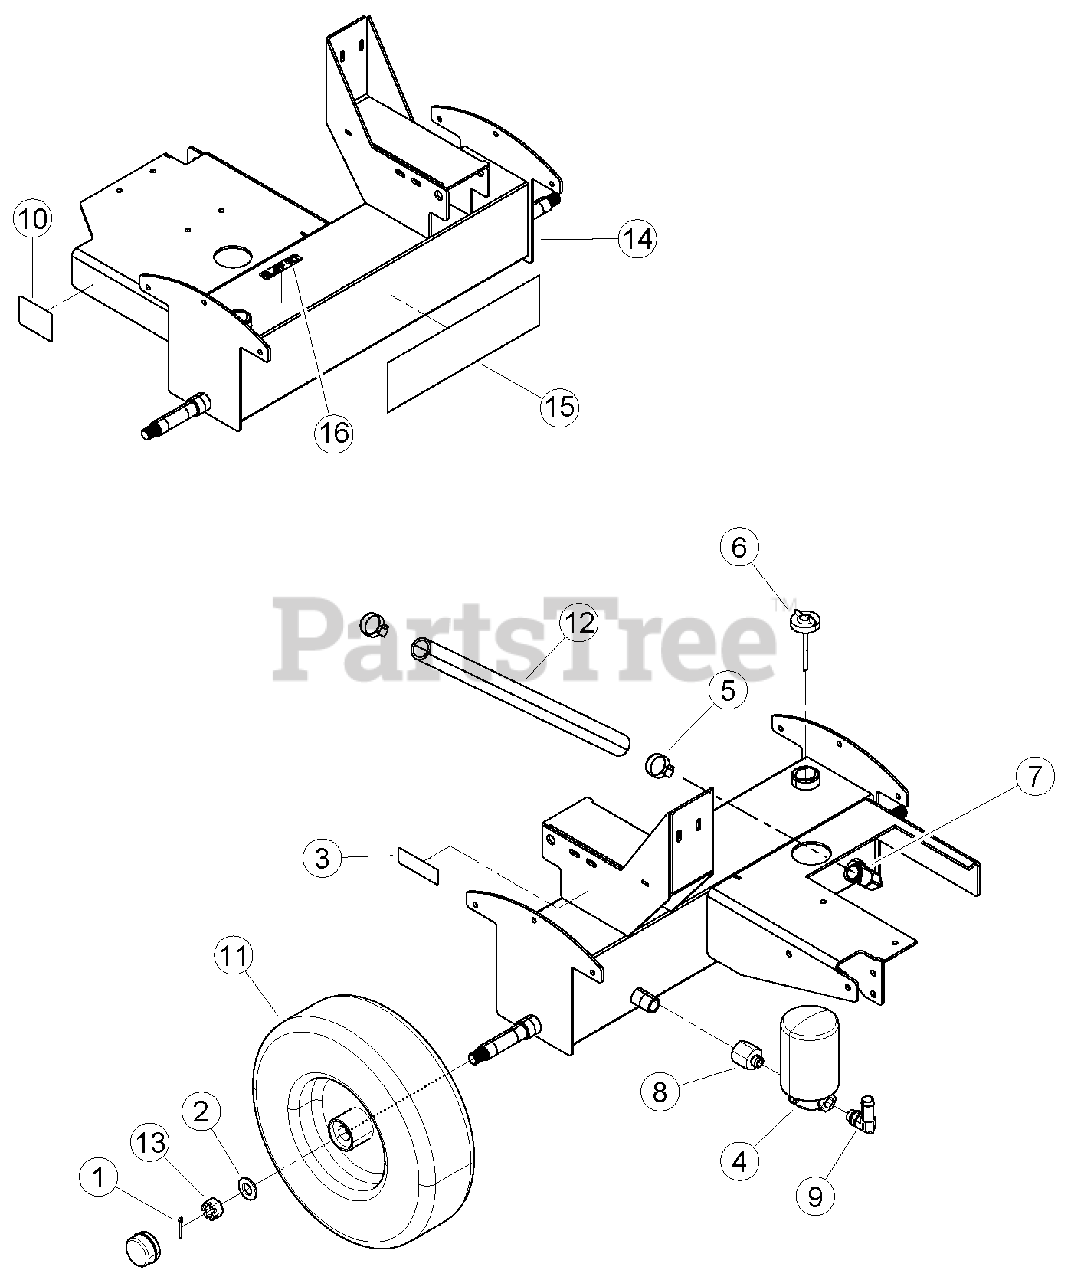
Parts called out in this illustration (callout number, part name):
1	PIN, 5/32 X 1-1/4 COTTER ZP
2	WASHER, 3/4 SAE FLAT ZP
3	DECAL, SERIAL NUMBER
4	FILTER, SPIN-ON
5	CLAMP, 1-1/4" HOSE
6	CAP, W/DIPSTICK
7	ADAPTER, 1" HOSE BEAD X -12 MORING
8	ADAPTER, -8 MORING / -12 FMNPT
9	ADAPTER, -8 MORING / 3/4" HOSE BARB 90
10	DECAL, 4.80-8 LOAD RATING
11	ASSEMBLY, TIRE 4.8-8
12	HOSE, 1.00 ID X 22 IN 100R4 HYD
13	NUT, SLOTTED 3/4-16 GRADE 2
14	ASSEMBLY, LOG SPLITTER TANK ATF
15	DECAL, ECHO BEARCAT 14.12 X 4.00
16	DECAL, ATF ONLY
